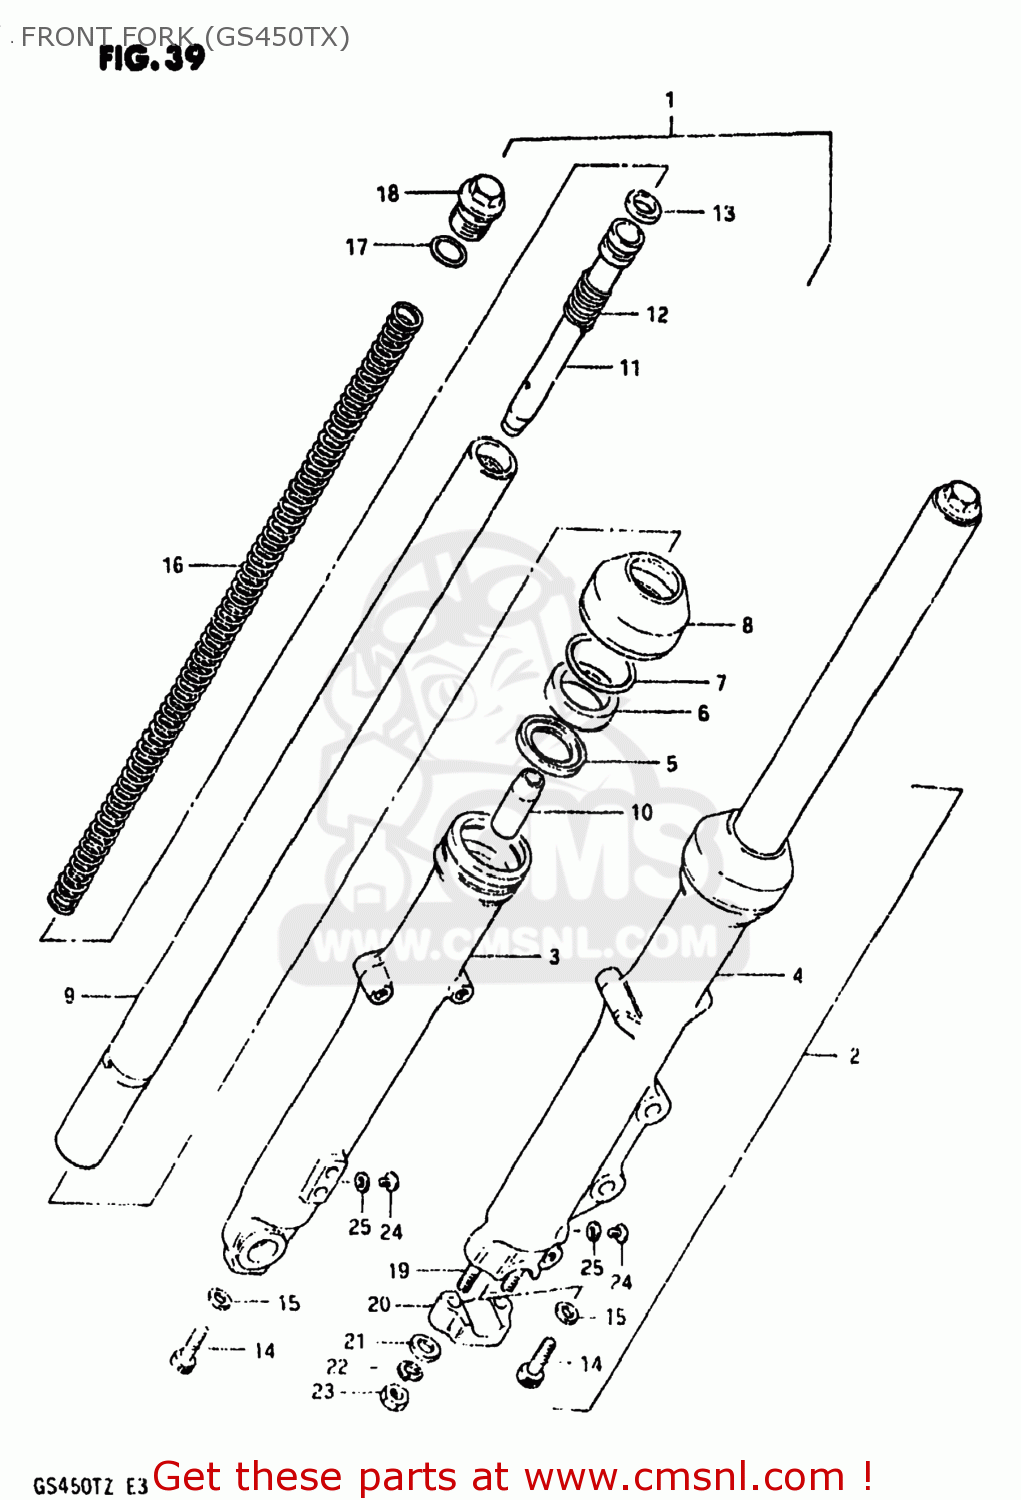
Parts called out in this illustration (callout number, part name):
1	DAMPER ASSEMBLY,RIGHT
2	DAMPER ASSEMBLY,LEFT
3	TUBE,FORK,OUTER,RIGHT
4	TUBE,FORK,LEFT,OUTER
5	SPACER,OIL SEAL
6	OIL SEAL,FRONT FORK
7	CIRCLIP,FORK OIL SEAL
8	DUST SEAL
9	TUBE,INNER
10	PIECE,OIL LOCK
11	CYLINDER,FRONT FORK
12	SPRING,REBOUND
13	RING,PISTON
14	BOLT(8X27)
15	GASKET (NAS)
16	SPRING
17	O RING
18	BOLT
19	STUD 8X25
20	HOLDER,AXLE
21	WASHER
22	LOCK WASHER
23	NUT (8MM)
24	SCREW 4X6
25	GASKET (NAS)
